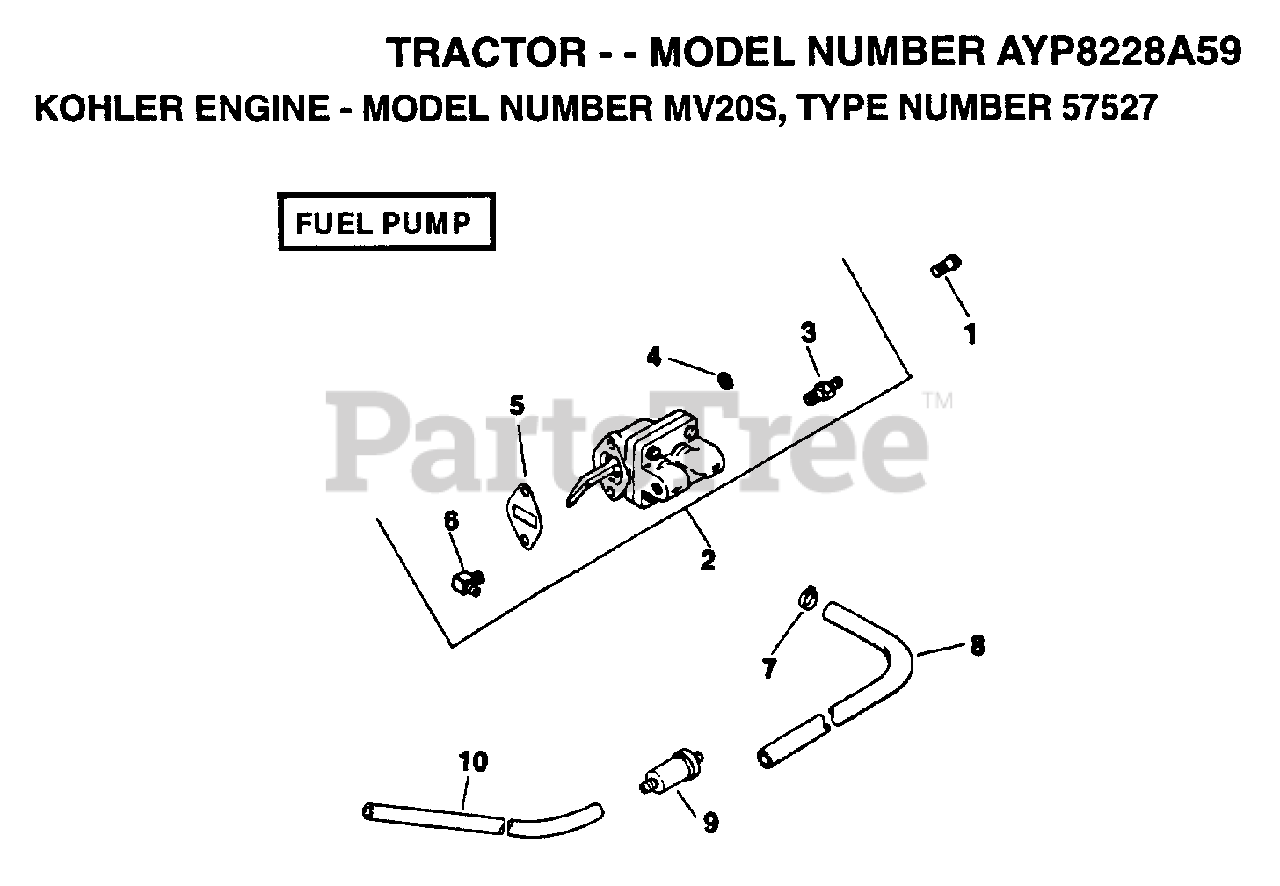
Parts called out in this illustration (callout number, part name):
3	CONNECTOR, HOSE
4	WASHER, PLAIN 1/4
7	CLAMP, HOSE
8	LINE FUEL 11-1/2"
10	LINE, FUEL 8"
